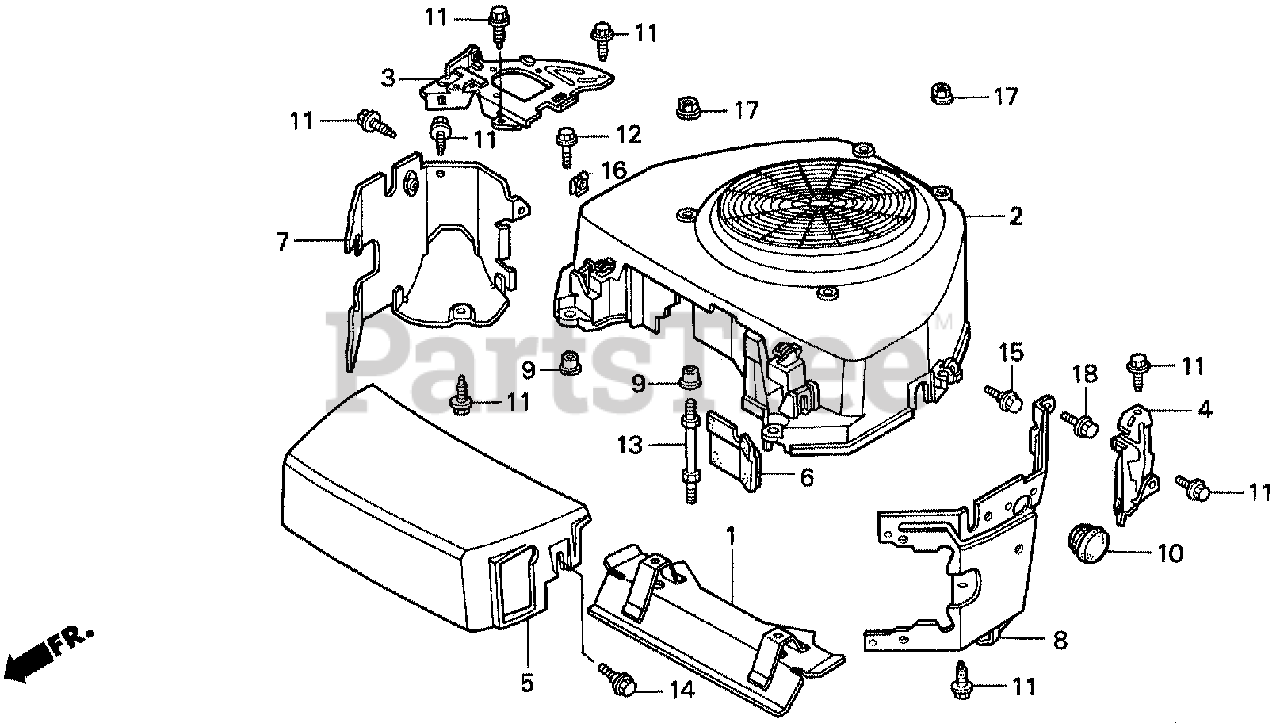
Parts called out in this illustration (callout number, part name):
1	PROTECTOR, EX. PIPE
2	COVER, FAN *R8* (BRIGHT RED)
3	PLATE, R. SIDE
4	PLATE, L. SIDE
5	HOOD, FAN COVER
6	PLUG, FAN COVER HOLE
7	SHROUD, R.
8	SHROUD, L.
9	COLLAR B, TAILLIGHT
10	GROMMET, DRAIN HOLE
11	BOLT, FLANGE (6X12) (CT200)
12	BOLT, FLANGE (6X23)
13	BOLT, STUD (6X75)
14	BOLT, FLANGE (6X20)
15	BOLT, FLANGE (6MM) (BLACK)
16	NUT, SPRING (6MM)
17	NUT, FLANGE (6MM)
18	BOLT, FLANGE (6X8)
